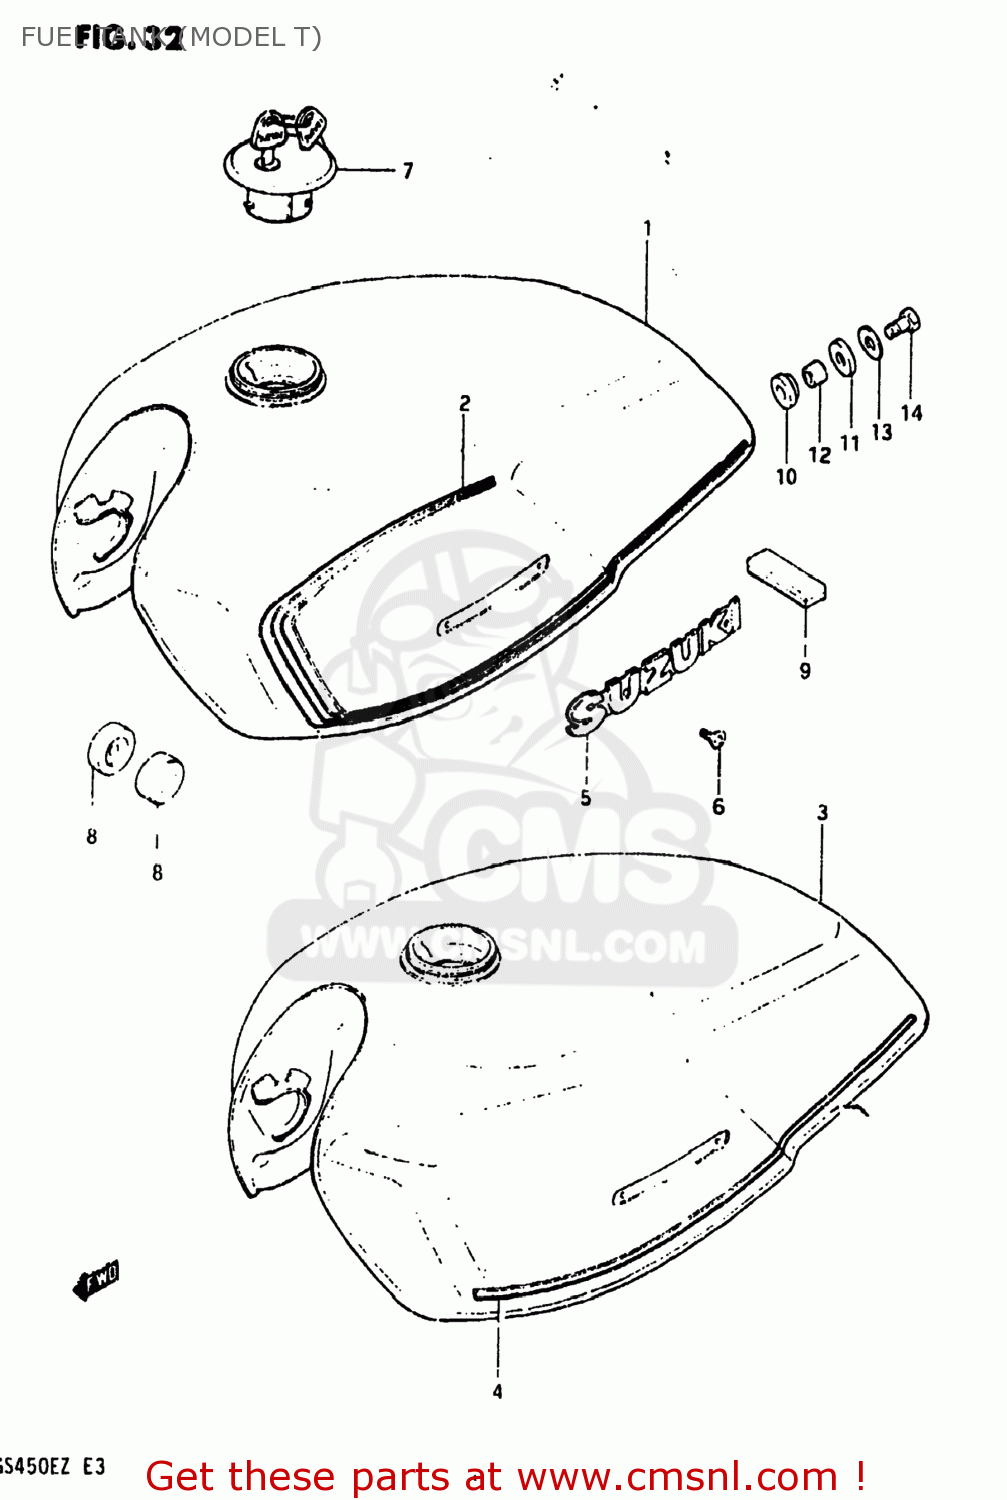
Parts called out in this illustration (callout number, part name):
1	TANK ASSEMBLY,FUEL
2	TAPE SET,FUEL TANK
3	TANK ASSEMBLY,FUEL
4	TAPE SET,FUEL TANK
5	EMBLEM,FUEL TANK
6	SCREW 3X6
7	CAP SET,FUEL TANK
8	CUSHION
9	CUSHION
10	CUSHION
11	CUSHION
12	SPACER(8.5X12X19)
13	WASHER (8.5X29X1.6)
14	BOLT (8X30)
